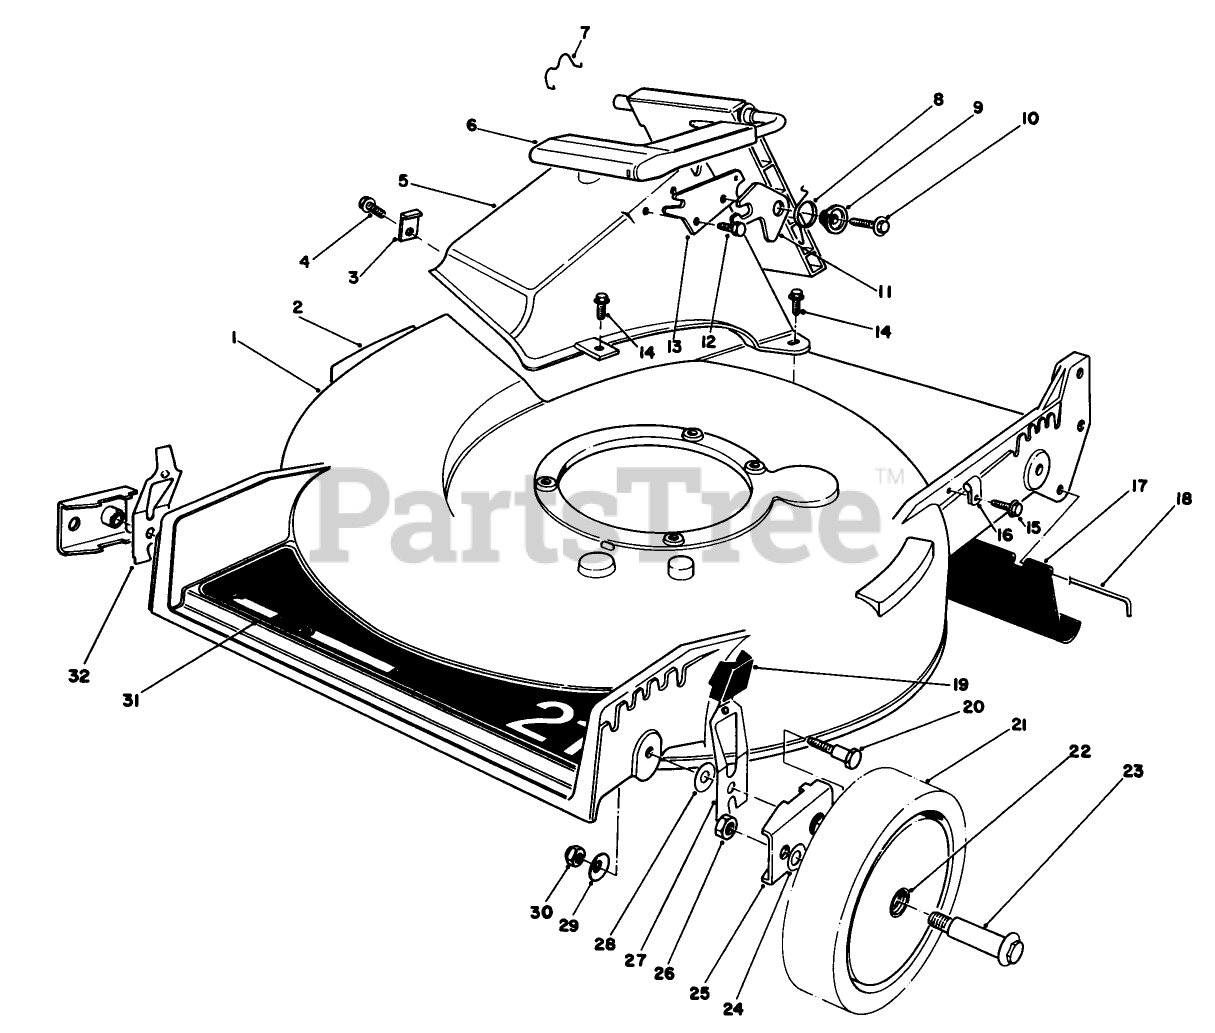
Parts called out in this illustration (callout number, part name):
1	21HP RB-SUZ HSG/DECAL
2	DECAL-DANGER
3	TUNNEL CLIP
4	SCREW
7	DOOR RET SPRING
8	TORSION SPRING
9	DOOR SPACER
10	SCREW-HWH
11	SAFETY LATCH
12	SCREW-PLASTITE
13	DOOR LATCH PLATE
14	SCREW-HWH
15	SCREW
16	CLAMP-CABLE
18	ROD-SHIELD
19	KNOB-ARM
20	PIVOT SCREW
22	BUSHING
23	WHEEL BOLT
24	WASHER
25	HP PIVOT ARM ASM
26	NUT-LOCK
28	WASHER-PIVOT
29	WASHER-BELLEVILLE
30	NUT-LOCK, NI
